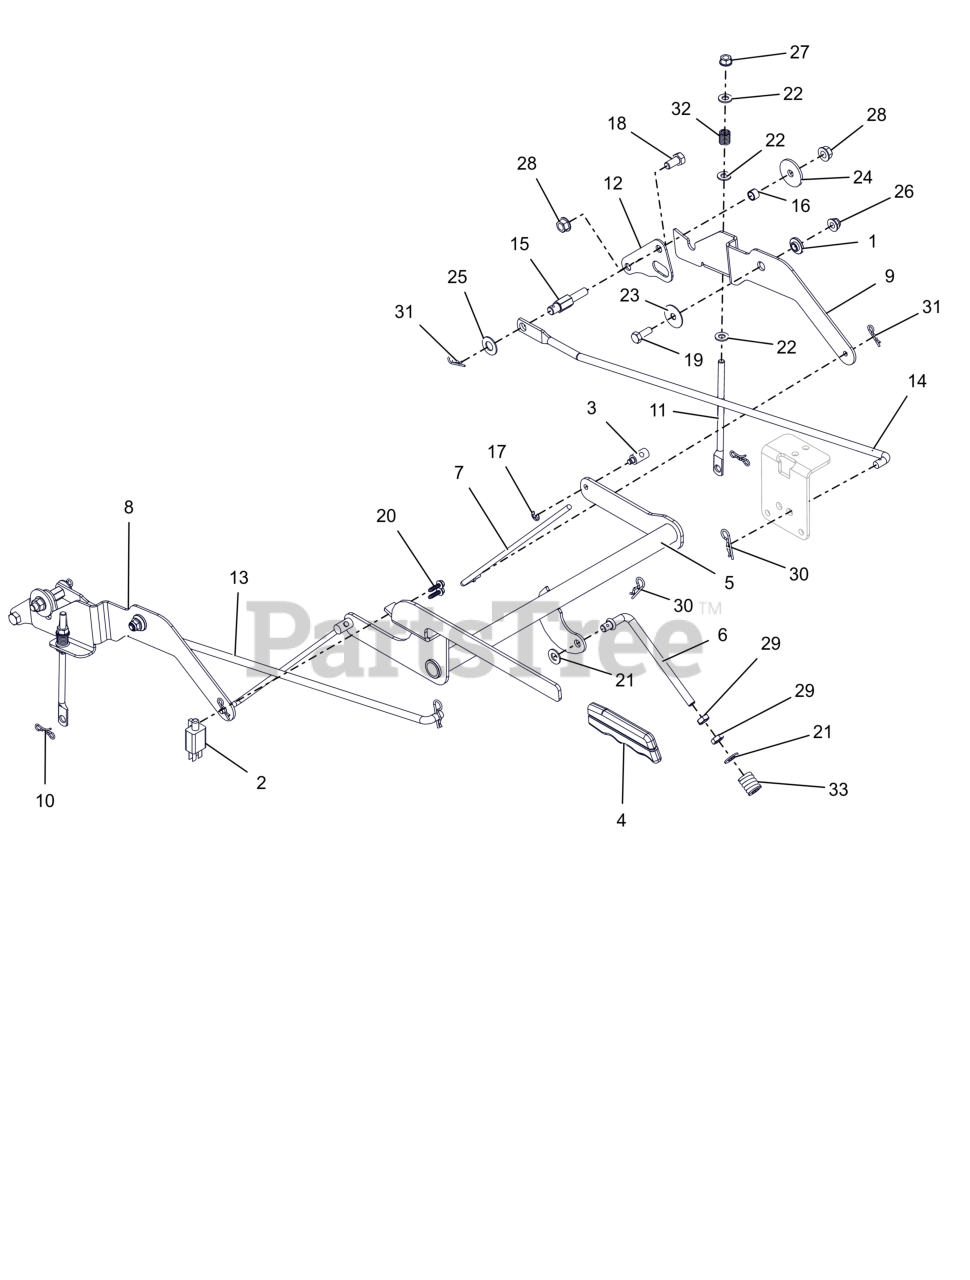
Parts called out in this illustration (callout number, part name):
1	BSHG, FLG .325X.499X.26X.88
2	SWITCH- DOUBLE POLE N.O./N.O.
3	TRUNION, 1/4-20
4	GRIP, PARKING BRAKE (YELLOW)
5	WLDMT, BRAKE LEVER
6	LINK, OVER CENTER, PARKING BRK
7	ROD, PARK BRAKE
8	INTERLOCK, RH BRAKE LINK
9	INTERLOCK, LH BRAKE LINK
10	PIN, BOWTIE #72 ZCC
11	LINK, TRANSAXLE BRAKE
12	PLATE, TRANSAXLE ADAPTOR
13	LINKAGE, STEERING - RH
14	ROD, STEERING LINKAGE LH
15	POST, STEERING LINK MOUNTING
16	SPCR, SLV .385X.500X.350
17	RG-RTNG-EXT .250X.025
18	BLT,HEX .38-16X.75 G5 ZCC
19	BLT, HEX .31-18X.875 G5 ZCC
20	SCR, PLASTITE-HWH 0.2 X 0.75 ZC120
21	WSHR,FLT .406X.812X.065 ZCC
22	WSHR,FLT .344X.688X.065 ZCC
23	WSHR, FLT .347X1.254X.048 ZCC
24	WSHR, FLT .380X1.50X.125 ZCC
25	WSHR, FLT .505X1.00X.062 ZCC
26	NUT,NYL-FLG .31-18 GF ZCC
27	NUT,LK-CTR-FLG .31-18 GF ZCC
28	NUT-LK-CTR-FLG .375-16 GF ZCC
29	NUT-JAM .375-16 G2 ZCC
30	PIN, HAIR .09 X 1.50 ZCC
31	PIN, HAIR #213 .08X1.19 ZCC
32	SPRING, COMPRESSION
33	SG-COMP .187X.56X1.62
